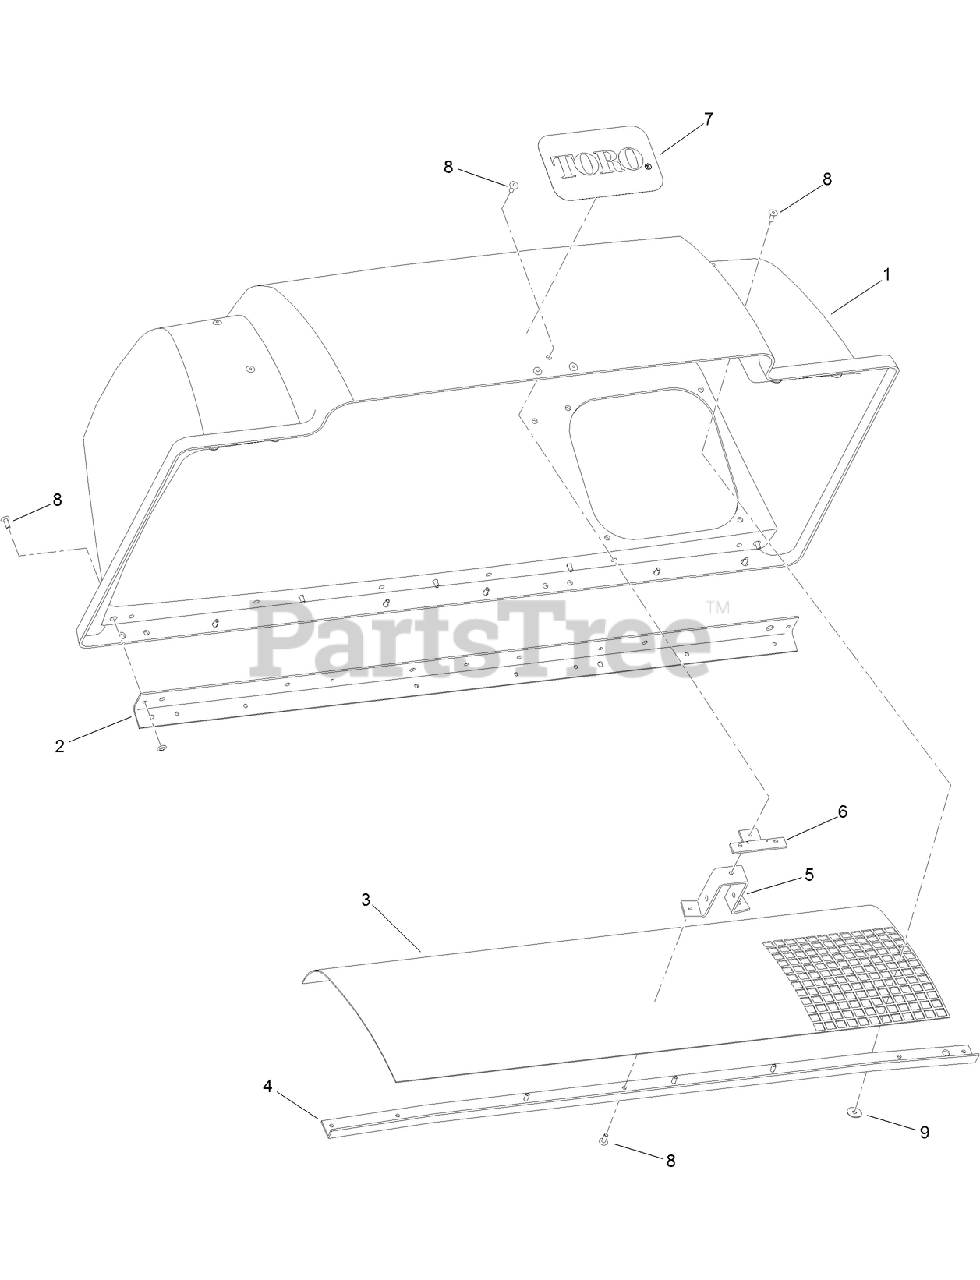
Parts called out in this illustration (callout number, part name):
1	TOP-BAGGER
2	STIFFENER-BAGGER, TOP
3	SCREEN-BAGGER
4	SUPPORT-SCREEN
5	ANCHOR-LATCH
6	REINFORCEMENT-LATCH
7	DECAL
8	RIVET-BLIND
9	WASHER-FLAT
